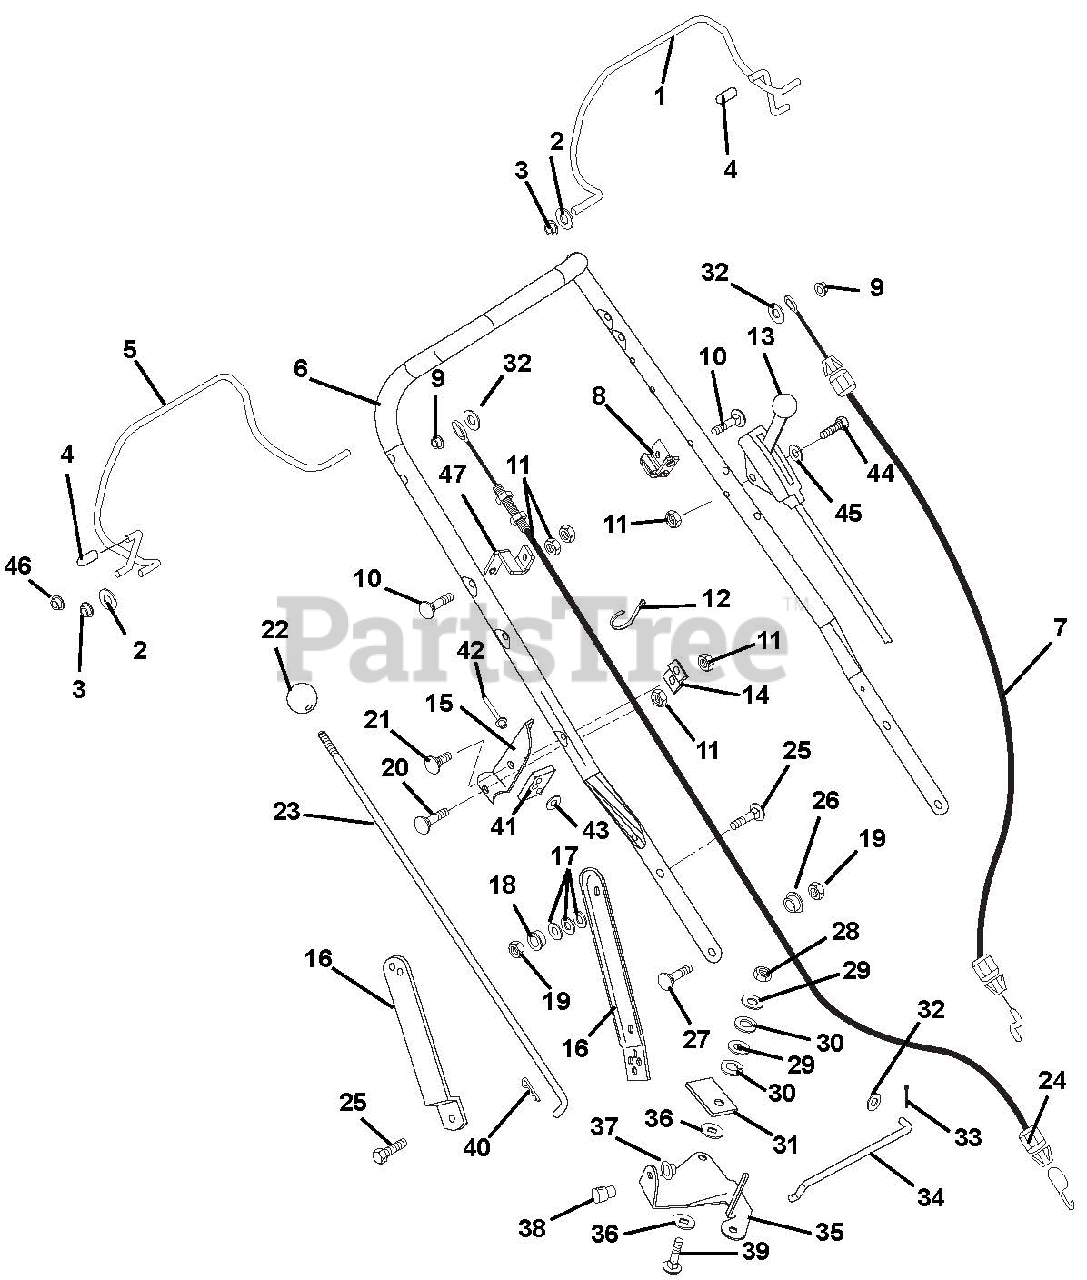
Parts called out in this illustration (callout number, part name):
1	BAIL, ENGINE WELDMENT
2	@WSHR-FL-STL.344X.688X.065YWZC
3	BSHG-FLG .325X.444X.440X.560
4	CAP, VINYL, .25 ID
5	BAIL, TRACTION (WLDMENT)
6	BAR, WBLM HANDLE
7	CABLE, ENGINE (BRIGGS/GXV)
7	CABLE, WBLM ENGINE
7	CABLE, ENGINE - ADJUSTABLE
8	ANCHOR, WBLM ENGINE CABLE
9	PUSH NUT, .25
10	BLT-RDHDXLSQNK.25-20X1.25 G5ZC
11	@NUT-LK-CTR .25-20 YWZC
12	CABLE TIE LG 5-1/2
13	CABLE, LOCKOUT CONTROL
14	BRACE, SPEED CONTROL
15	BRACKET, SPEED CONTROL
16	LINK, HANDLEBAR ADJUSTMENT LH
16	LINK, HANDLEBAR ADJUSTMENT RH
17	WASHER, BELLEVILLE YWZC
18	BSHG-FLG .325X.500X.513X.875
19	@NUT-LK-CTR .31-18 YWZC
20	@BLT-RDHDSQNK .25-20X1.50 G5YZ
21	@BLT-RDHDSQNK .25-20X.50 G5YZ
22	KNOB, BALL 5/16-18 X 1.5
23	ROD-SPEED CONTROL
24	CABLE, WBLM TRACTION
25	@BLT-RDHDSQNK .31-18X1.00 G5YZ
26	BSHG, FLG .325X.499X.26X.88
27	@BLT-RDHDSQNK .31-18X.75 G5YZ
28	@NUT-LK-CTR .38-16 YWZC
29	@WSHR-FL-STL.406X.812X.065 YWZ
30	WSHR-LK .375X.115 HVY YWZC
31	PRESSURE FLANGE
32	@WSHR-FL-STL.281X.62X.065 YWZC
33	@PIN-CTR .06X.50 EXTPRSQCT YWZ
34	SHIFT LINK
35	BELL CRANK - SPEED CONTROL
36	FRICTION WASHER
37	CAP, 3/8 ROD YWZC
38	SWIVEL
39	@BLT-RHDSSQNK .38-16X1.25 G5YZ
40	PIN-HAIR INT .08X.18X1.18 YWZC
41	SUPPORT PAD
42	RVT .187X.575 DOME AL BLACK
43	@WSHR-FL-STL.219X.50X.049 YWZC
44	BLT-RDHDSQNK .25-20X1.75 G5YZ
45	@WSHR-FL-STL.250X.56X.049 YWZC
46	NUT-PUSH .312 DIA. PAL
47	ANCHOR, CABLE
